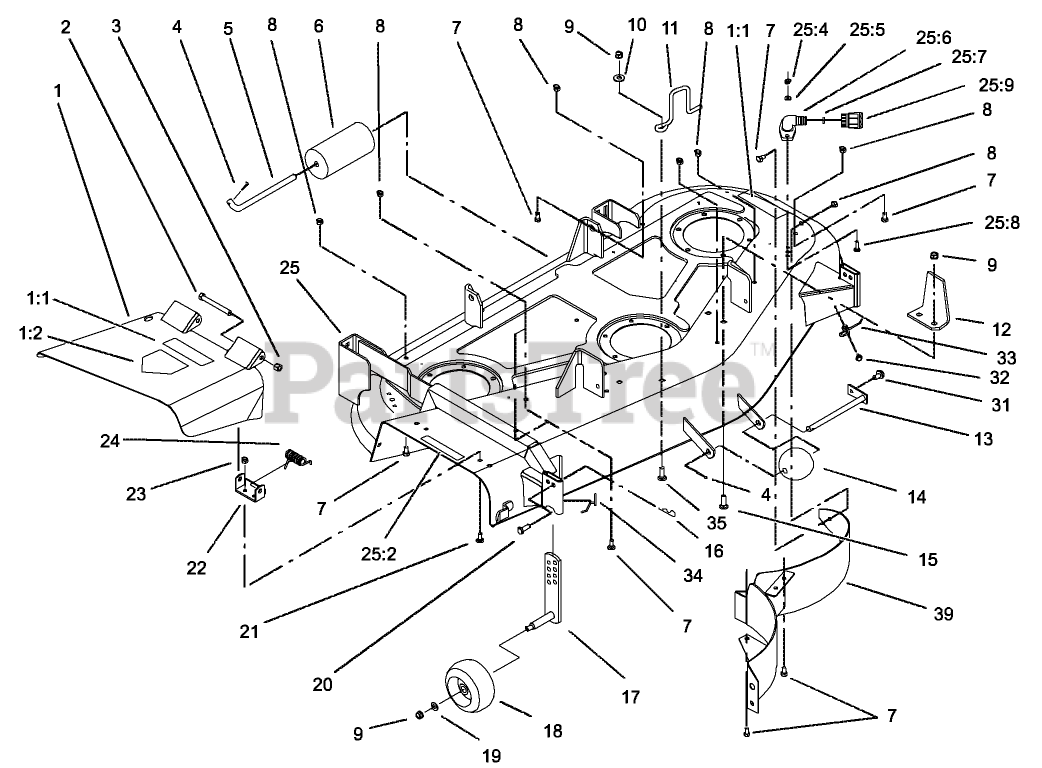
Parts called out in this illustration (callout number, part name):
1:1	DECAL-DANGER
1:2	DECAL-DANGER
2	SCREW-HH
3	NUT-HEX
4	PIN-COTTER
5	SHAFT-ROLLER, REAR
6	ROLLER-DECK
7	SCREW-HH
8	NUT-LOCK, NI
9	NUT-LOCK, NI
10	WASHER
13	SHAFT ASM
14	ROLLER
15	BOLT-CARR
16	PIN-HAIR
17	GAGE-WHEEL
19	WASHER-FLAT
20	PIN-CLEVIS
21	SCREW-CARR
22	BRACKET-PIVOT
23	NUT-LOCK, NI
24	SPRING
25:2	DECAL-CAUTION
25:2	DECAL-DANGER
25:4	NUT-LOCK, NI
25:5	WASHER-FLAT
25:7	O-RING
25:8	BOLT-CARR
25:9	CONNECTOR-HOSE
31	SCREW-HWHTF
32	SCREW-HHFTF
34	SPRING-GAGE WHEEL, RH
35	SCREW-CARR
39	BAFFLE ASM-MULCH, LH
